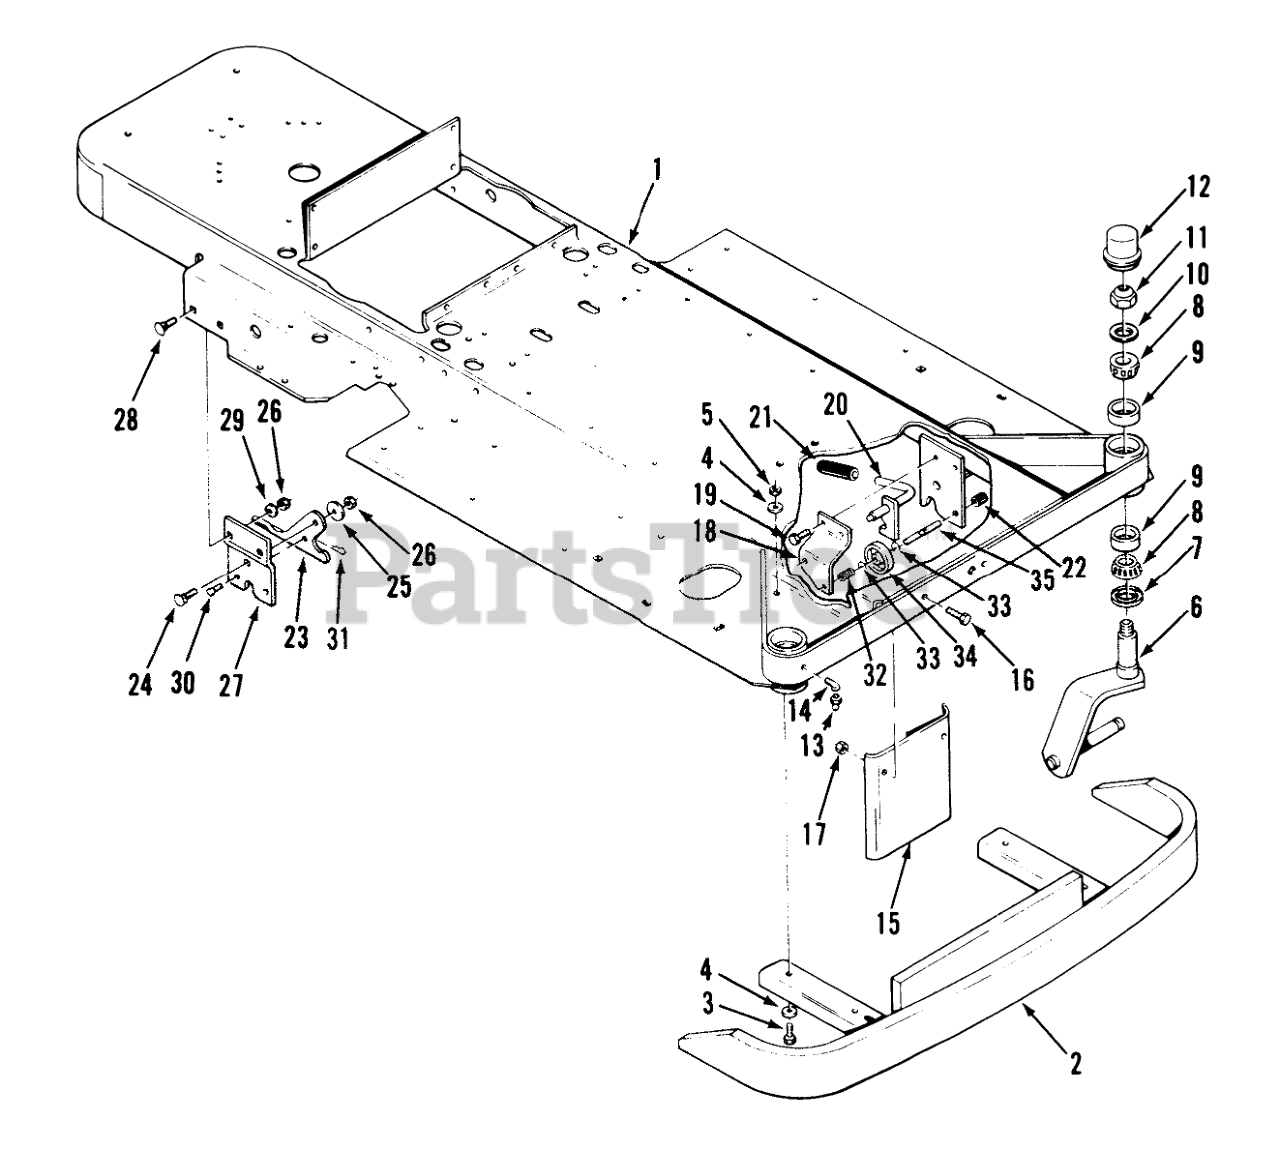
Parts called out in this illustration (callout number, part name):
1	Frame
2	Bumper-Front
3	BOLT
4	Washer
5	NUT
6	SPINDLE WELDMENT
7	Seal
8	Bearing
9	Cup
10	Washer
11	Nut
12	DUST CAP
13	Fitting-Grease
14	ELBOW 1/8 STREET
15	Shield
16	Bolt
17	Nut
18	Bracket RH
19	Screw
20	Latch RH
21	GRIP
22	CAP-ROD, PLUNGER
23	PLATE-LATCHING
24	Bolt
25	WASHER
26	NUT
27	Hitch Plate
28	Bolt
29	Washer
30	Pin
31	Hairpin
32	SPRING
33	RING-RETAINING
35	ROD-LOCK
